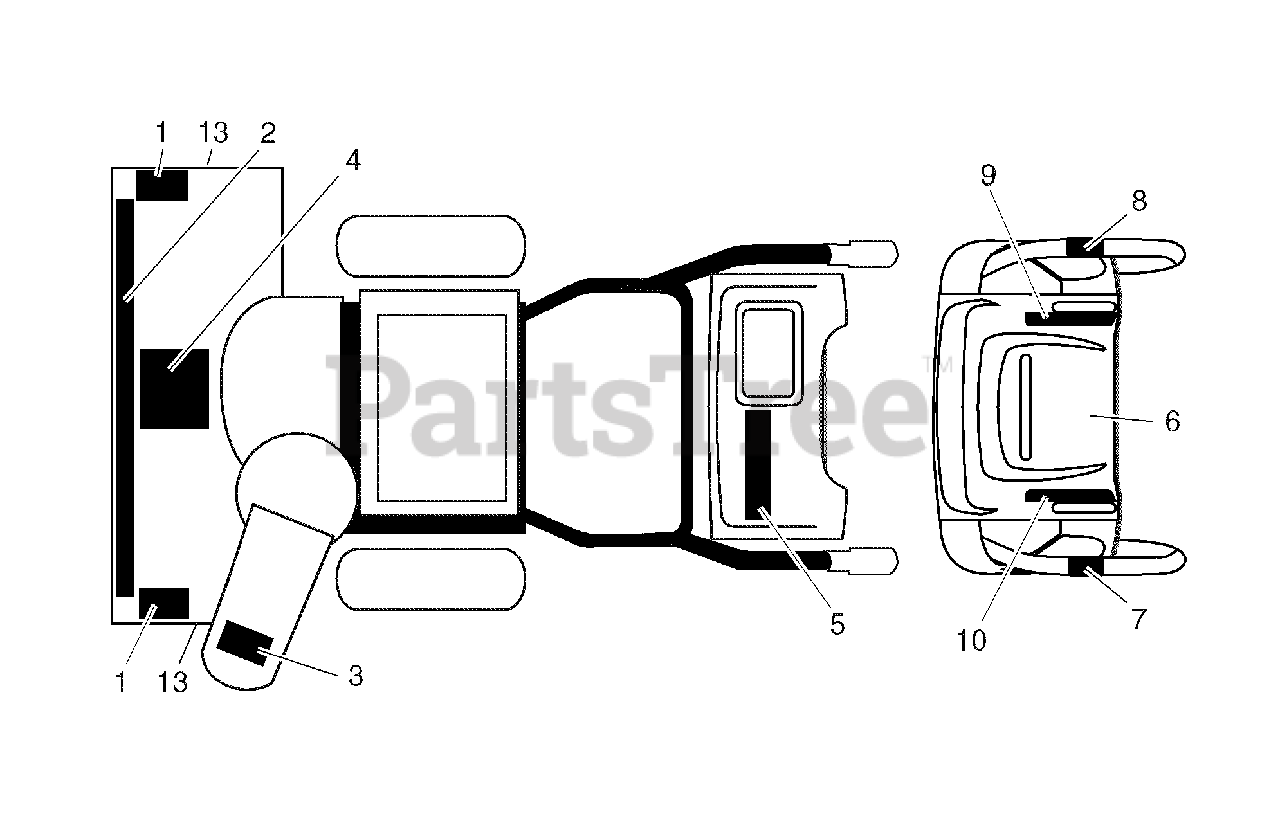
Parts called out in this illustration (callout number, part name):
1	Decal, Danger
2	Decal, Husqvarna
3	Decal, Danger, Deflector
4	Decal, Danger
5	Decal, Husqvarna, 8527SBEB
6	Decal, Instruction
7	Decal, Traction Lever
8	Decal, Auger Lever
9	Decal, Speed Control
10	Decal, Remote Deflector
13	Decal, Husqvarna, Crown
